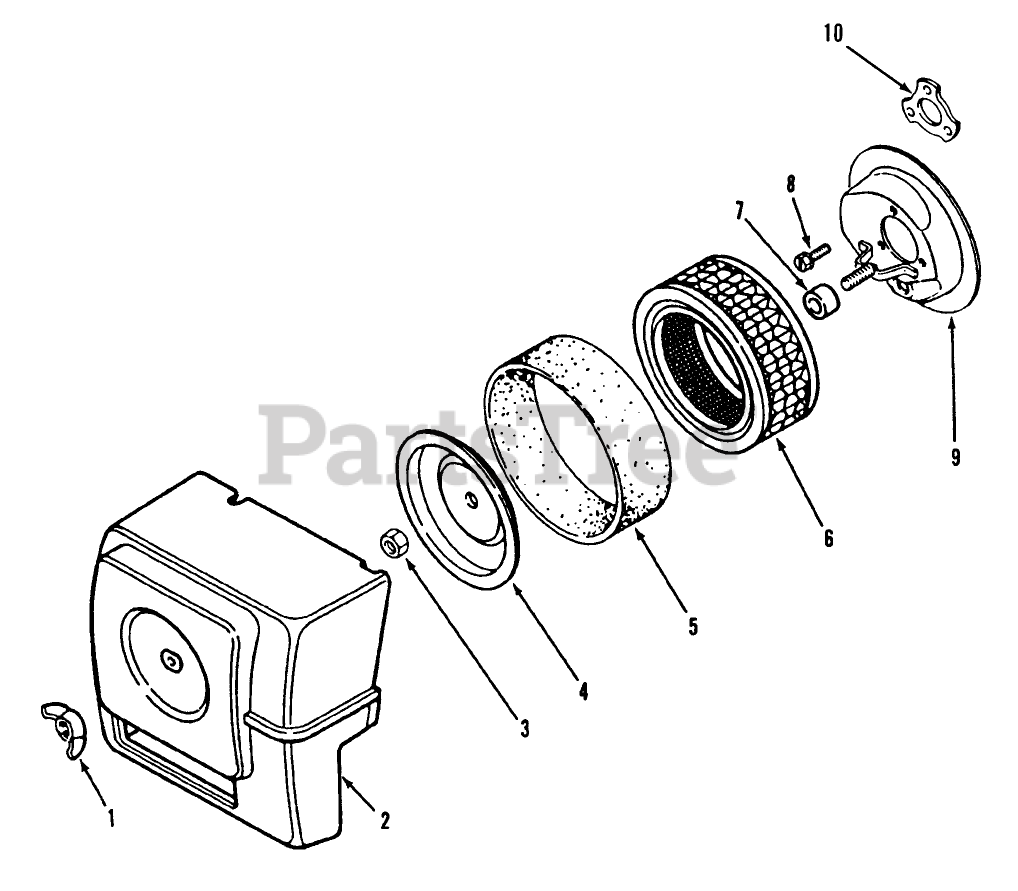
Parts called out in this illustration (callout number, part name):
1	Wing Nut 1/4-20
2	Air Cleaner Cover
3	Jam Nut
4	Cover-Element
5	Element
6	Element
8	Screw
9	Base-Air Cleaner
10	Air Horn Gasket
